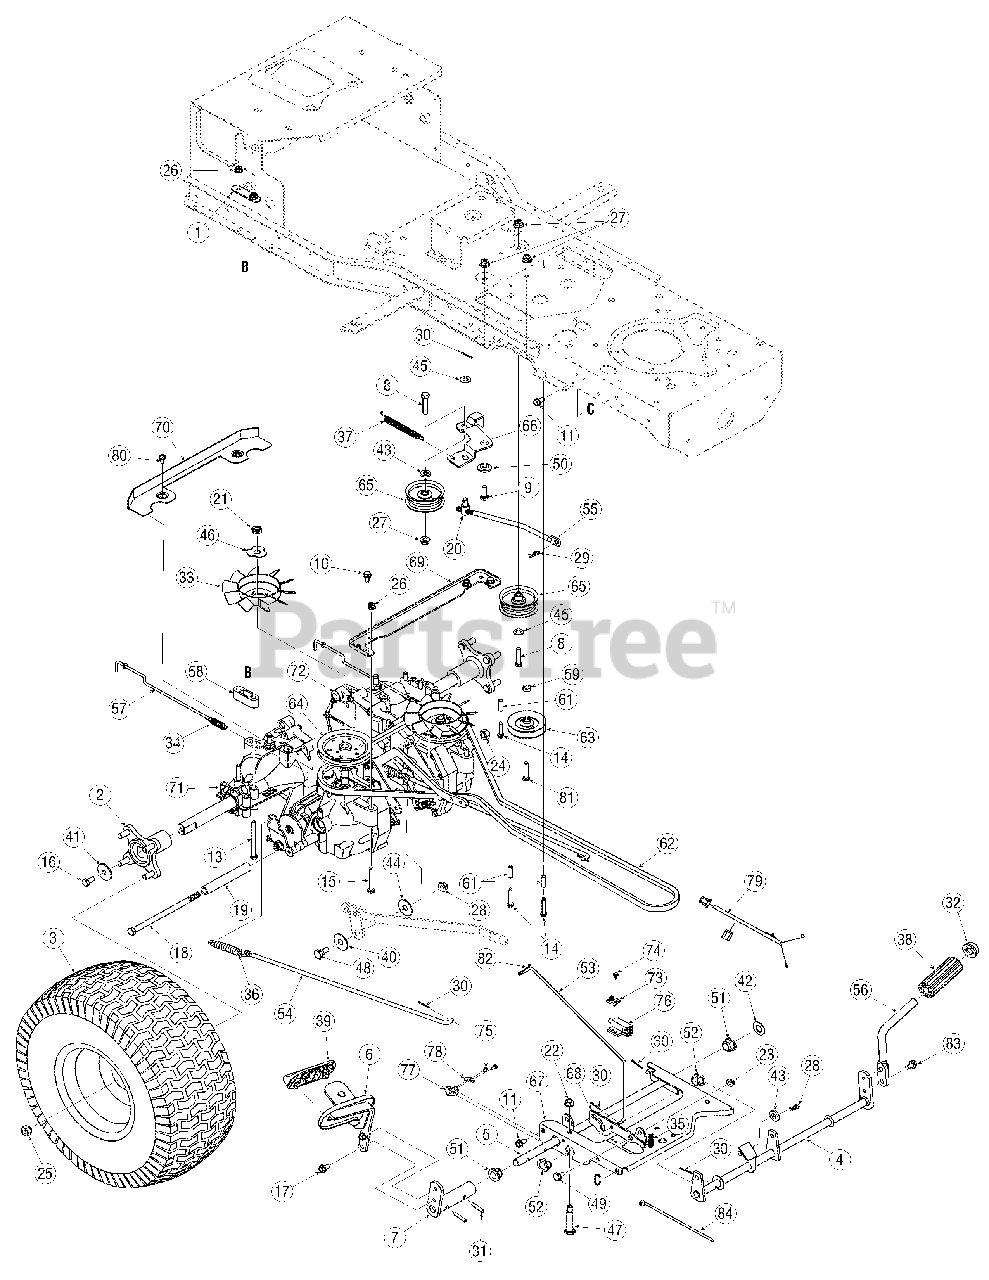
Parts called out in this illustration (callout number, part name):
2	Hub, Wheel
3	Wheel Assembly
3	Valve, Tubeless Air
4	Shaft Assembly, Brake Control
5	Shaft Assembly, Hydro Control Pedal
6	Pedal Assembly, Hydro Control
10	Screw, Hex Wash Hd. Tapp, 5/16-18 x .5
11	Screw, Hex Wash Hd. Tapp, 5/16-12 x .75
13	Screw, Hex Cap, 5/16-18 x 3.5 Gr5
14	Screw, Hex Wash Hd. Tapp, 1/4-20 x 1.625
15	Screw, Hex Cap, 5/16-18 x 2.25 Gr5
16	Screw, Hex Cap Lock, 3/8-16 x .75 Gr5
17	Screw, Hex Wash Hd. Tapp, 5/16-18 x .75
18	Screw, Hex Cap, 7/16-14 x 8.5 Gr5
19	Spacer, .479 x .75 x 4.97
20	Ferrule, 3/8-24 x .375 Dia.
21	Nut, Hex Jam Insert Lock, 1/2-20 Gr5
22	Nut, Hex Flange Top Lock, 3/8-16 GrF
23	Nut, Hex Flange Lock, 5/16-18 Gr5
24	Nut, Hex Lock, 7/16-14 GrA
25	Nut, Lug, 7/16-14
26	Nut, Hex Flange Insert Lock, 5/16-18 GrF
27	Nut, Hex Flange Insert Lock, 3/8-16 GrF
28	Nut, Hex Lock, 3/8-16
29	Pin, Internal Cotter
30	Pin, Cotter, 3/32 x 1/0
31	Pin, Spirol, .25 x 1.25
32	Cap, Push, 5/8
33	Fan, Hydro
34	Spring, Extension, .48 x 2.03
35	Spring, Compression, .405 x 1.17
36	Spring, Extension, .59 x 4.0
37	Spring, Extension, .56 x 5.52
38	Pad, Foot, 4.0 in. Lg
39	Pad, Hydro Control Pedal
40	Washer, Flat, .531 x 1.75 x .09
41	Washer, Flat, .39 x 1.5 x .134
42	Washer, Flat, .625 x 1.0 x .067 HT
43	Washer, Flat, .407 x .812 x .135 HT
44	Washer, Flat, .406 x 1.5 x .105
45	Washer, Flat, .406 x .812 x .051
46	Washer, Hydro Lock
47	Bolt, Shoulder, 3/8-16: .5 x 2.0
48	Bolt, Shoulder, .496 x .336: 3/8-16
49	Bolt, Shoulder, .435 x .160 : 5/16-18
50	Spacer, Shoulder, .625 ID x .169
51	Bearing, Hex Flange
52	Bearing, Hex Flange, .625 ID Split
53	Rod, Park Brake
55	Rod, Drive Engage
58	Spacer, T-Axle
59	Spacer, .38 x .625 x .265
61	Spacer, .26 x .372 x 1.42
62	V-Belt, 88.4
63	Pulley, V Type Drive, 3.06
64	Pulley, V Type, 4.5
65	Pulley, Flat Idler, 2.75
71	Transmission, Hydro RH
72	Transmission, Hydro LH
73	Plate, Switch
74	Screw, Hex Wash Hd. Tapp, #10-16 x .5
75	Screw, Hex Wash Hd. Tapp, #8-18 x .5
76	Switch, Brake
77	Switch, Reverse
78	Plate, Insulator Nut
79	Harness, Reverse Jumper
80	Screw, Hex Wash. Hd. Tapp, 1/4-20 x .5
81	Screw, Hex Head Cap, 3/8-16 x 2
82	Cotter Pin, Bow Tie
83	Screw, TT, 5/16-18 x .750
84	Cable Tie
